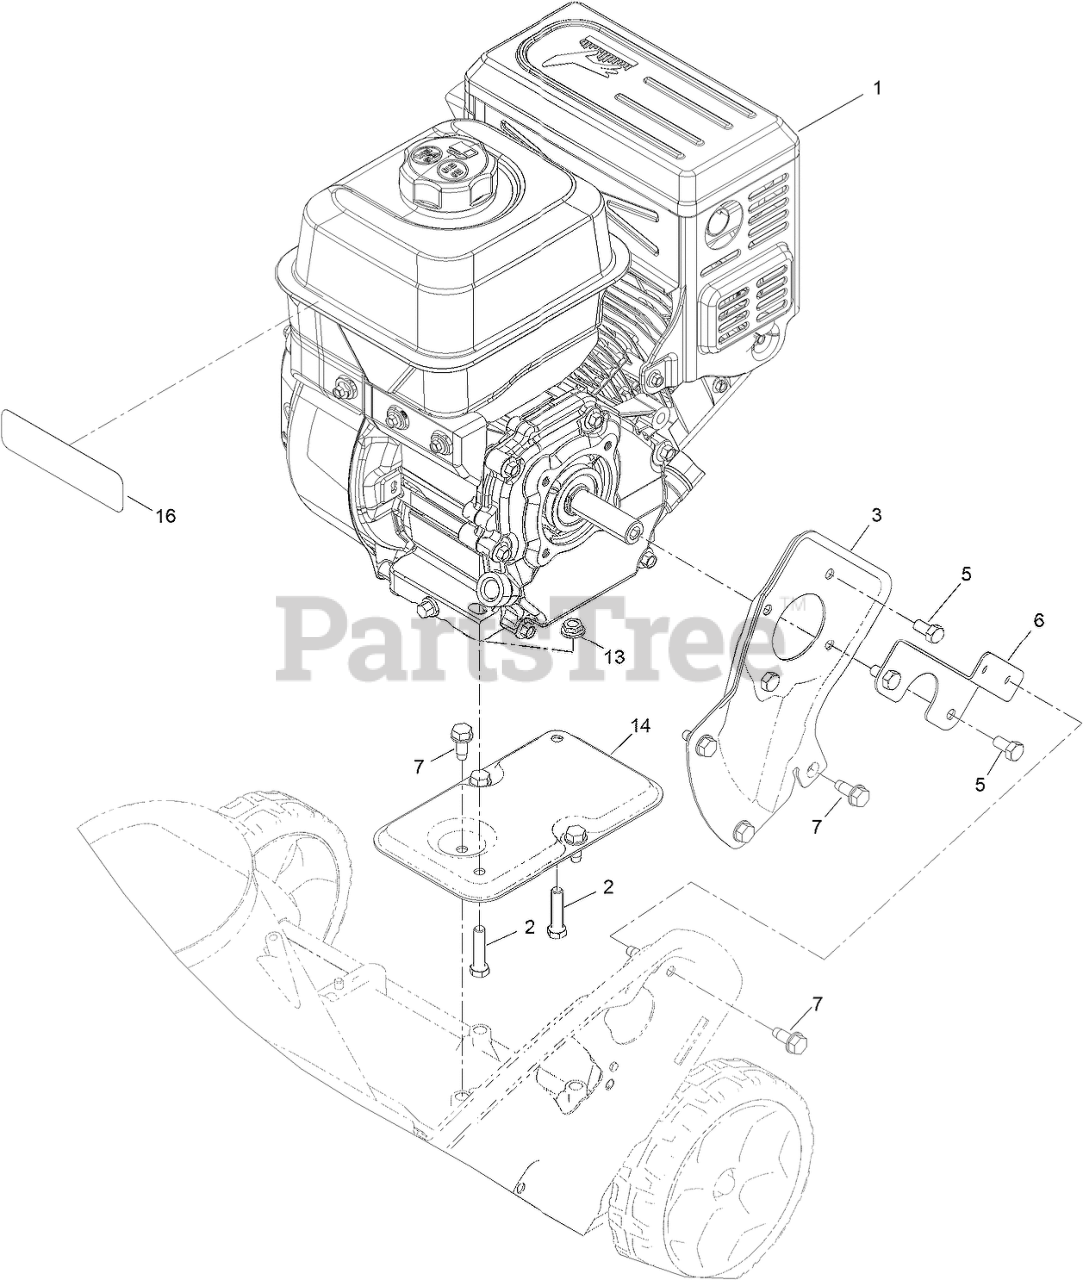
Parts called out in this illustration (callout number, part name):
1	ENGINE-G250FDS-4
2	SCREW-HH
3	PLATE-ENGINE, PTO
5	BOLT
6	SUPPORT-ENGINE, SIDE
7	SCREW-THD ROLL, HWH
13	NUT-HF
14	SUPPORT-ENGINE
16	DECAL-ENGINE
